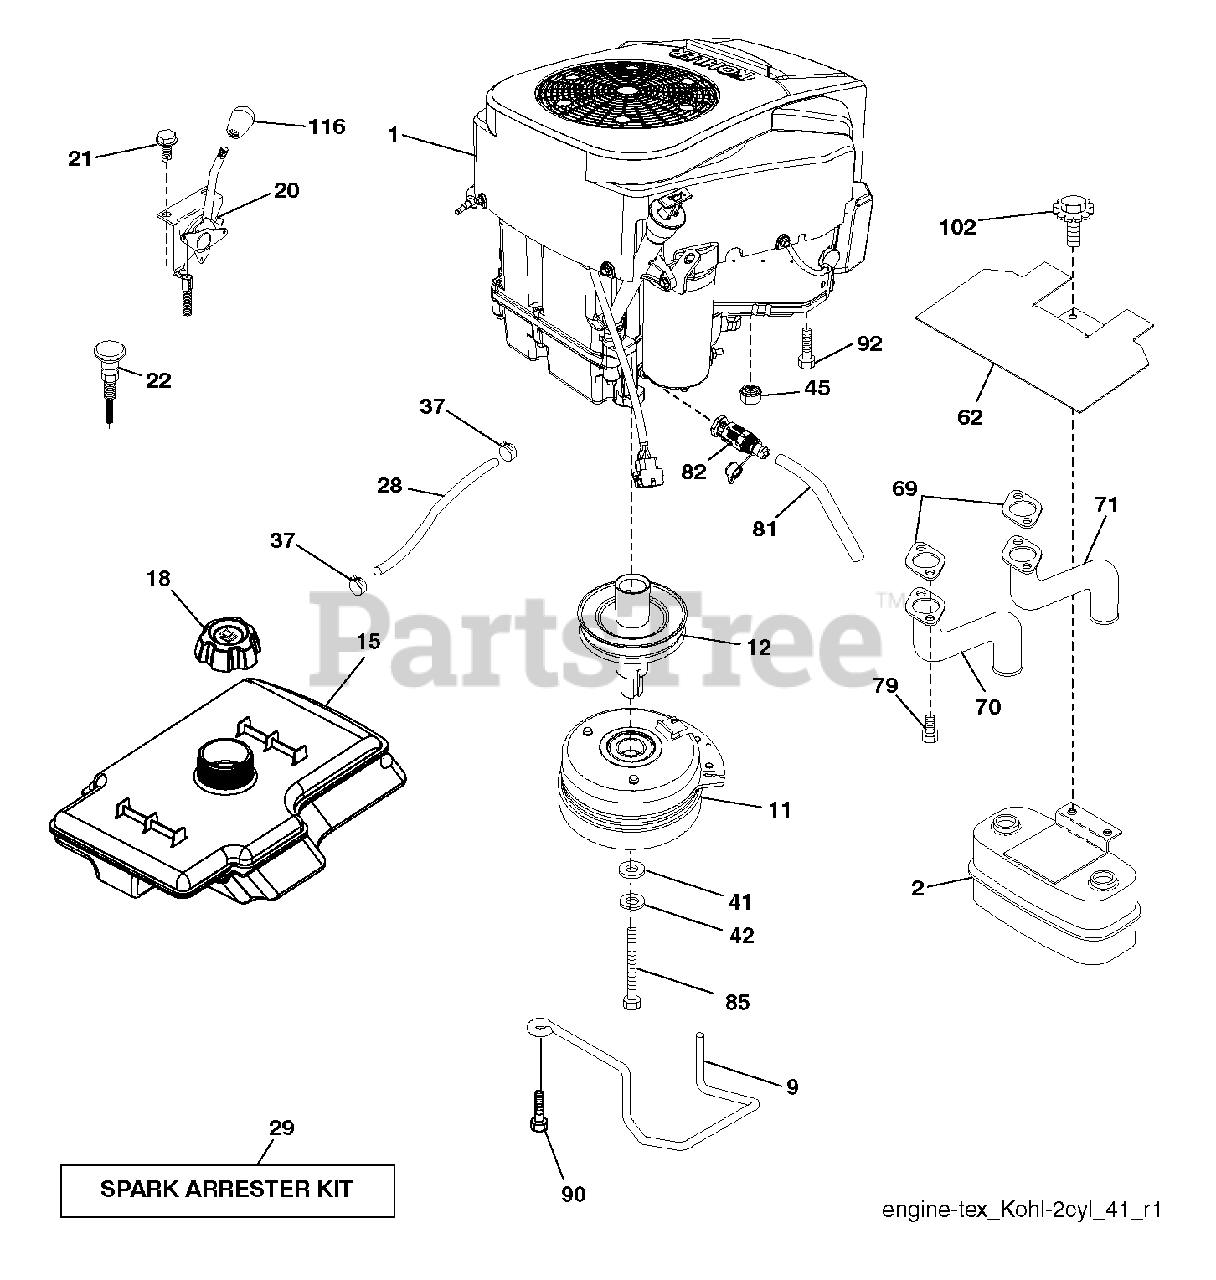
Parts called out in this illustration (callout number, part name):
2	MUFFLER.ASM.TWN.EXTNDED.DFLCTR
9	KEEPER BELT ENGINE
11	CLUTCH. 5.0 PD. 2.5 OFFSET
12	PULLEY.EXTENDED.SHAFT.GROUND
15	FUEL TANK
18	CAP.ASSY.FUEL.3".N-EPA.BLK.428
20	CONTROL.THROTTLE.PRO.KOHLER
21	SCREW.#10 X 0.750.BOS
22	CONTROL.CHOKE.ERGO.PUSH-IN.BLA
28	LINE.FUEL.64"REAR.EMIS
29	KIT.SPARK ARRESTOR 794945 B&S
37	HOSE CLAMP
42	LOCKWASHER
45	NUT
62	SHIELD.HEAT.MUFFLER
69	GASKET.EXHAUST.KOHL.CV18-CV26
70	PIPE.EXHAUST.LH.CV18/20
71	PIPE.EXHAUST.RH.CV18/20
79	SCREW.SOCKET HD.5/16-1
81	TUBE, DRAIN OIL ASM.
82	VALUE.OIL.DRAIN
85	BOLT.HEX.7/16-20 X 5
90	SCREW 3/8-16X1
92	SCREW 3/8-16X1
102	SCREW
